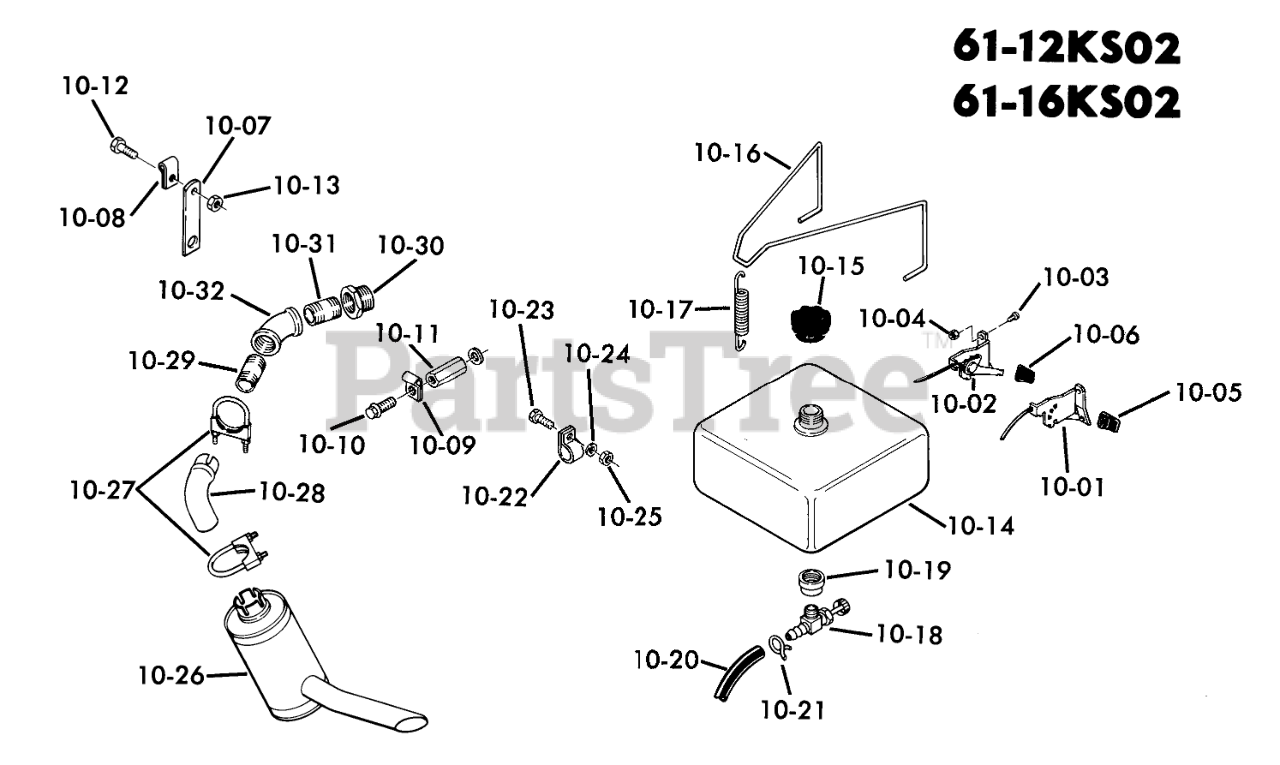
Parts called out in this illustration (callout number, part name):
10-01	Choke Control
10-02	THROTTLE CONTROL
10-03	SCREW
10-04	#10-24 Kep-Nut
10-05	KNOB-CHOKE
10-06	KNOB-THROTTLE
10-07	Strap
10-08	THROTTLE CONTROL CLP
10-09	Clip
10-10	Screw
10-11	Special Nut
10-12	Screw
10-13	Nut
10-14	ASSY-FUEL TANK
10-15	Cap
10-16	HOLD DOWN WIRE
10-17	CLUTCH SPRING
10-18	VALVE-FUEL
10-19	BUSHING
10-20	Fuel Hose
10-21	Clamp
10-22	CLAMP-HOSE
10-23	Bolt
10-24	WASHER 5/16 SAE
10-25	Nut
10-26	MUFFLER
10-27	ASSY-MUFFLER CLAMP
10-28	MUFFLER INLET TUBE
10-29	NIPPLE
10-30	REDUCER 1 1/4-1
10-31	Nipple 1" Pipe
10-32	ELBOW
